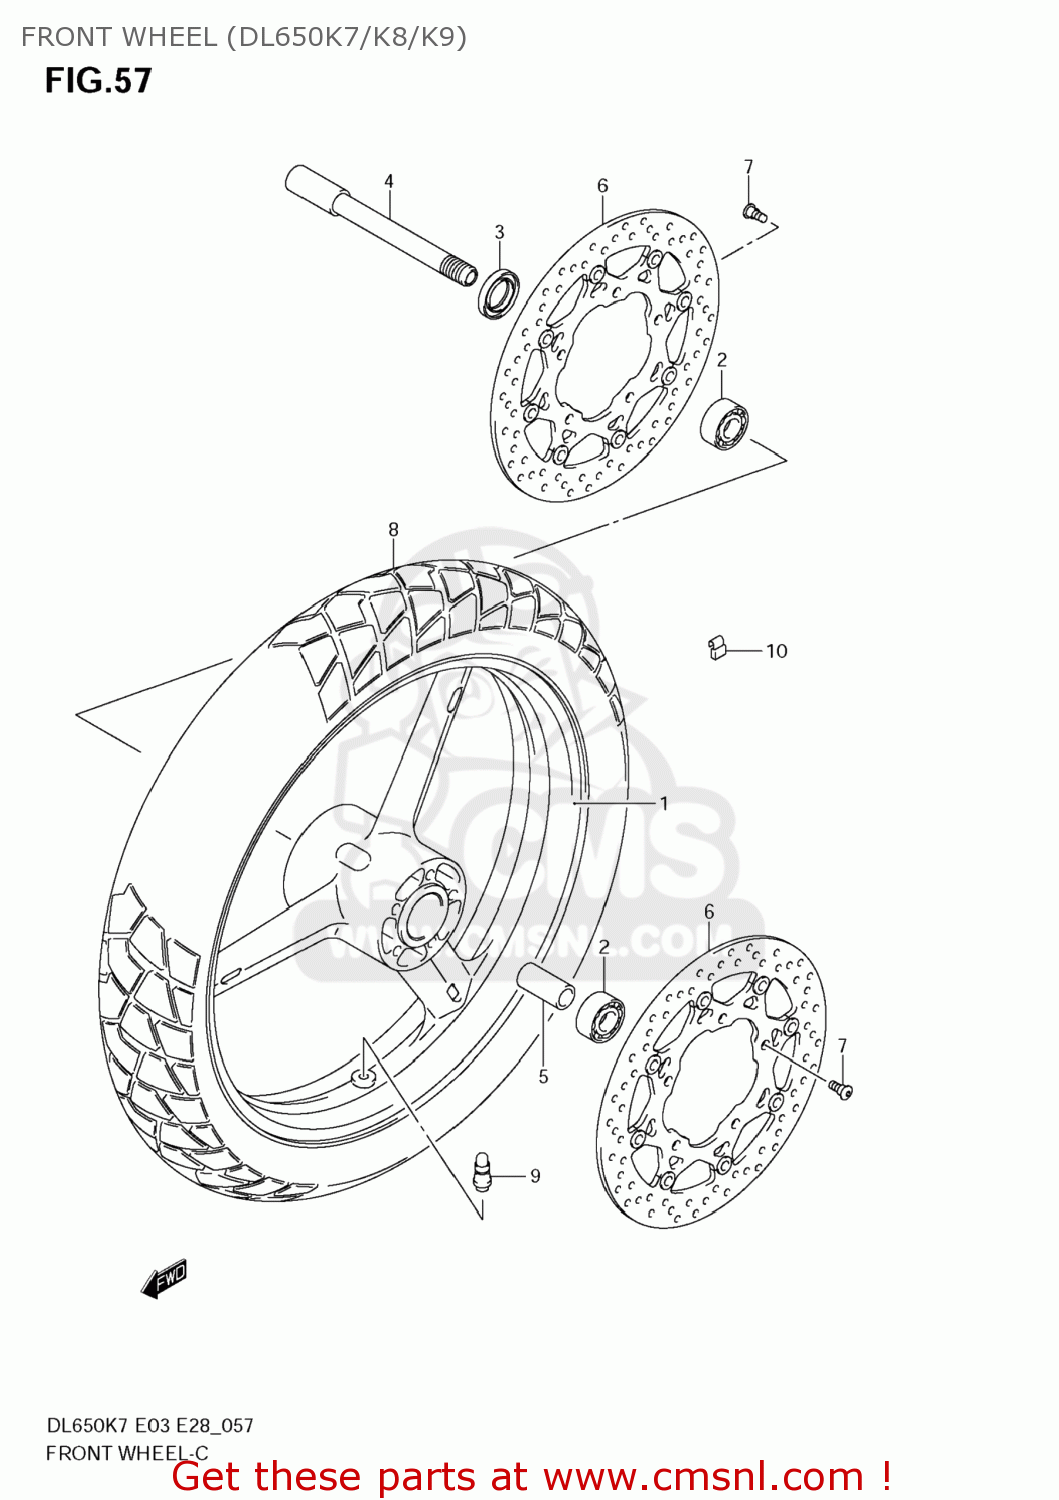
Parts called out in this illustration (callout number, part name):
1	WHEEL,FR(19M/C
2	BEARING
3	SEAL,OIL(22X40X7)
4	AXLE,FR
5	SPACER(17.5X25X88)
6	DISC,FRONT BRA
7	BOLT(8X21)
8	TIRE,FRONT,110
9	VALVE ASSY,WHEEL RIM(TR412)
10	WEIGHT,WHEEL BALANCE 10G
